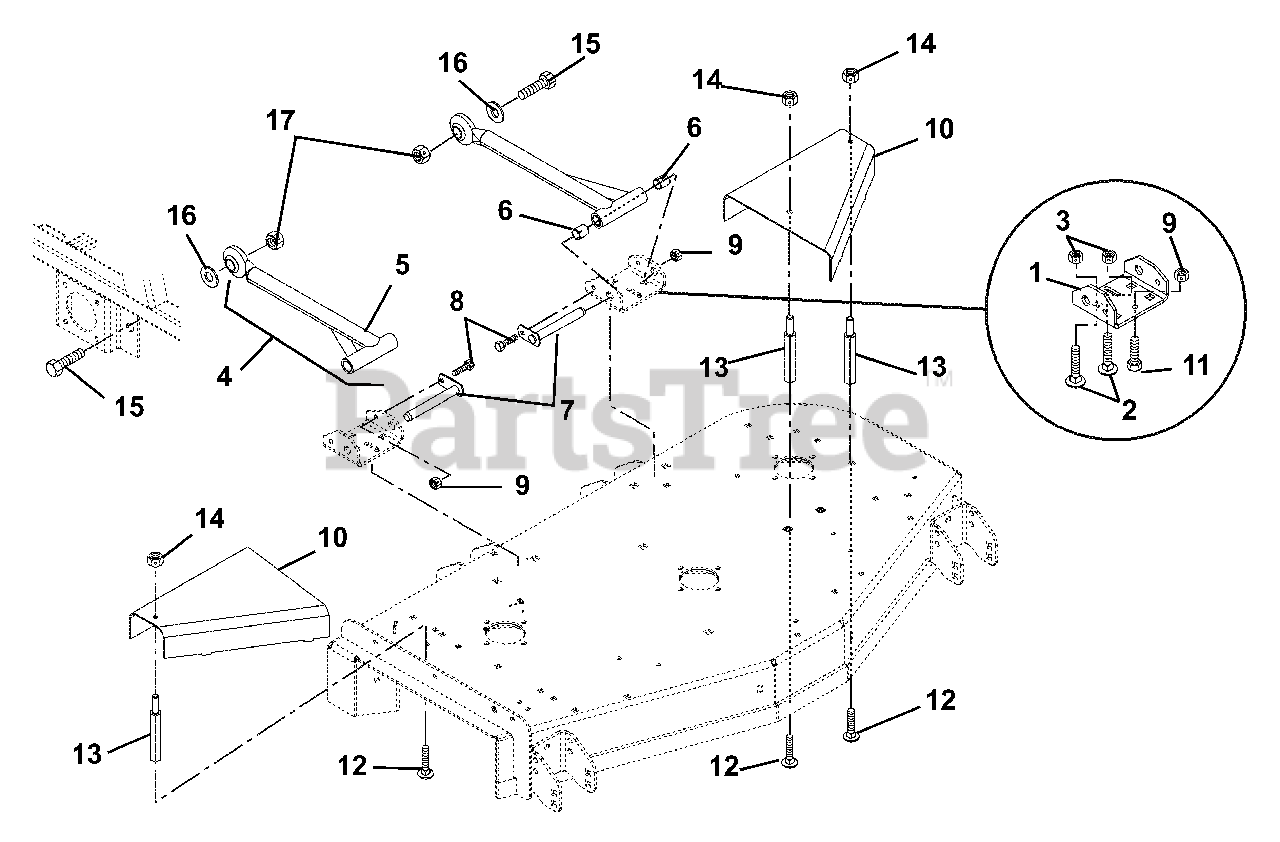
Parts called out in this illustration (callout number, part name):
1	BRACKET, MOWER MOUNT (REAR)
2	@BLT-RDHDSQNK .50-13X.75 G5YZ
3	NUT-LK-CTR-JAM .50-13 YWZC(ND)
4	ASSEMBLY, MOWER MOUNTING ARM
5	WMT, MOWER MTG ARM - BLACK
6	BRG, .750 X .875 X 1.000
7	WELDMENT, MOWER MTG. PIN
8	@BLT-HEX .38-16X1.00 GR5 YWZC
9	@NUT-LK-TOP-FLG .38-16 YWZC
10	GUARD, PULLEY LH
11	@BLT-RDHDSQNK .38-16X.75 G5YZ
12	BLT,RDHDSQNK .31-18X.75 LOCTIT
13	STANDOFF, 2.75 X 5/16-18
14	@NUT-LK-TOP-FLG .31-18 YWZC
15	BLT-HEX .875-9X2.75 GR5 YWZC
16	WSHR-FL-STL .890X1.500X.1196YZ
17	NUT-LK-CTR .875-9 YWZC
